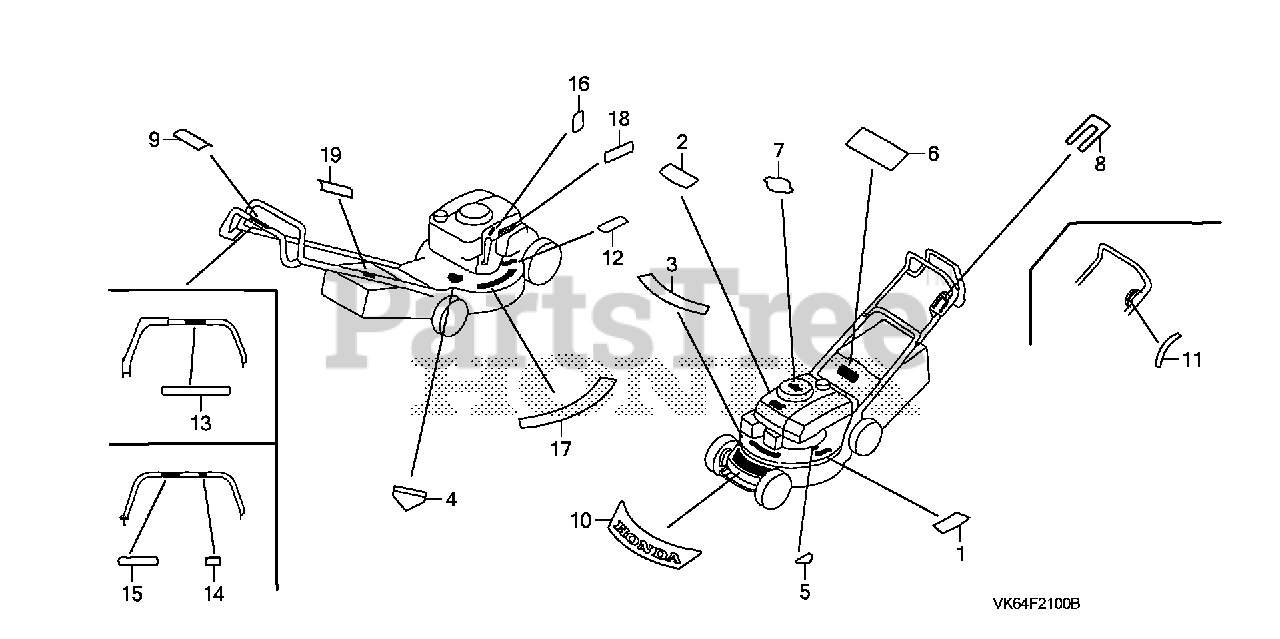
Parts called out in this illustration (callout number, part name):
2	MARK, EMBLEM
4	LABEL C, HOUSING CAUTION
6	LABEL, WARNING (ENGLISH)
8	MARK, THROTTLE INDICATION (ENGLISH)
9	MARK, CLUTCH INDICATION (ENGLISH)
10	MARK, HONDA
12	LABEL, HEAT WARNING
14	MARK, BLADE CONTROL
15	MARK, BLADE CONTROL (ENGLISH)
16	MARK, OIL CAUTION
18	MARK, OIL RECOMMENDED
